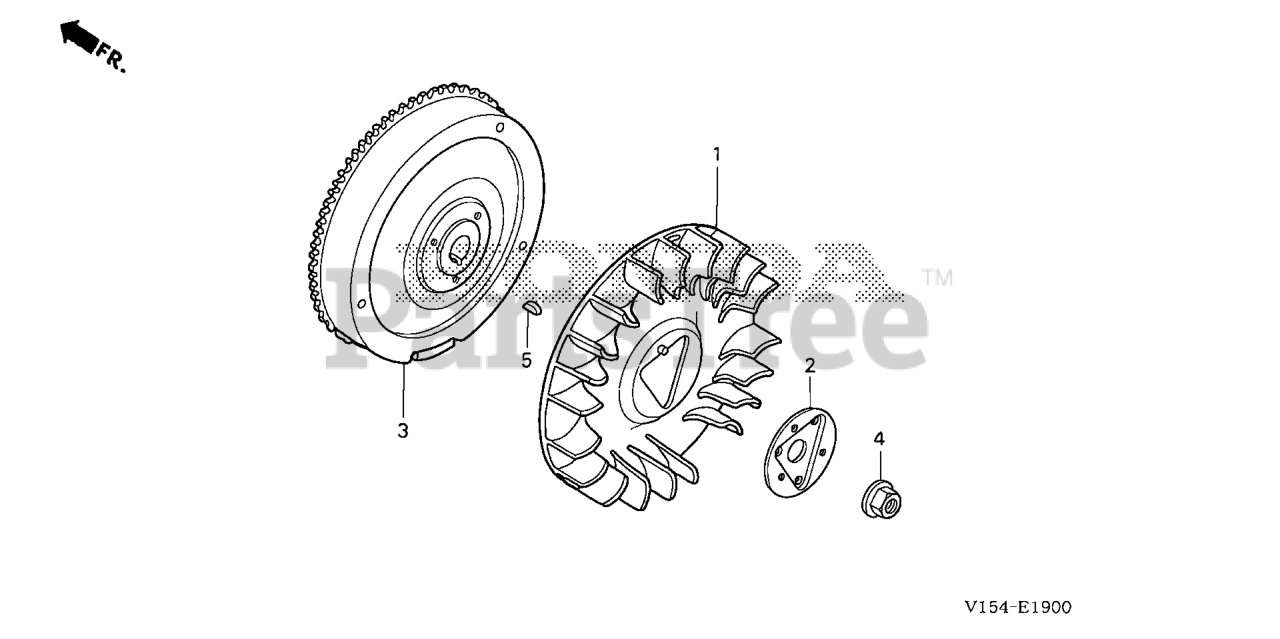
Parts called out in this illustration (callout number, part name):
1	FAN, COOLING
2	PLATE, COOLING FAN SETTING
3	FLYWHEEL (SEL)
4	NUT, SPECIAL (16MM) (1)
5	KEY, SPECIAL WOODRUFF (25X18)
